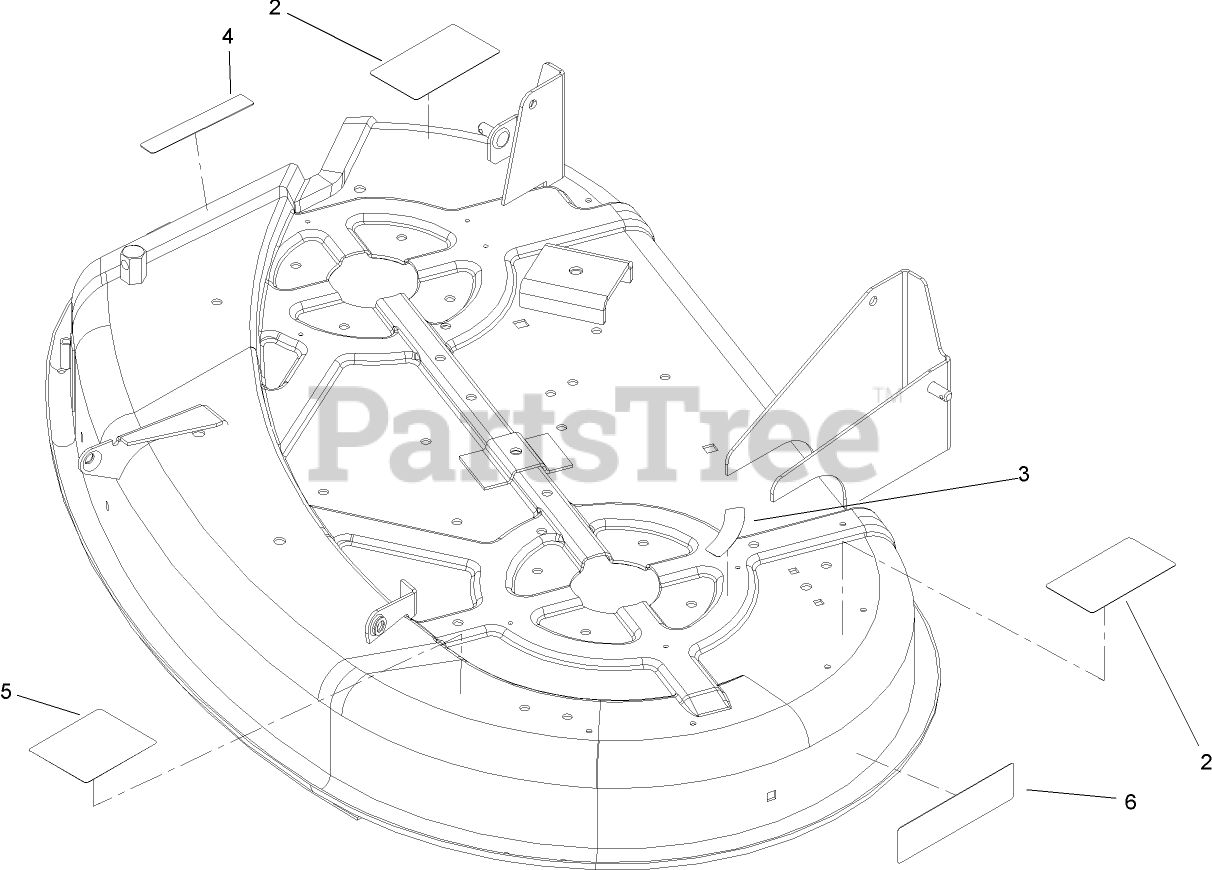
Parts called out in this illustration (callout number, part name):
2	DECAL-DANGER
3	DECAL-DANGER, SHIELD
4	DECAL-DANGER
5	DECAL-ROUTING, BELT
